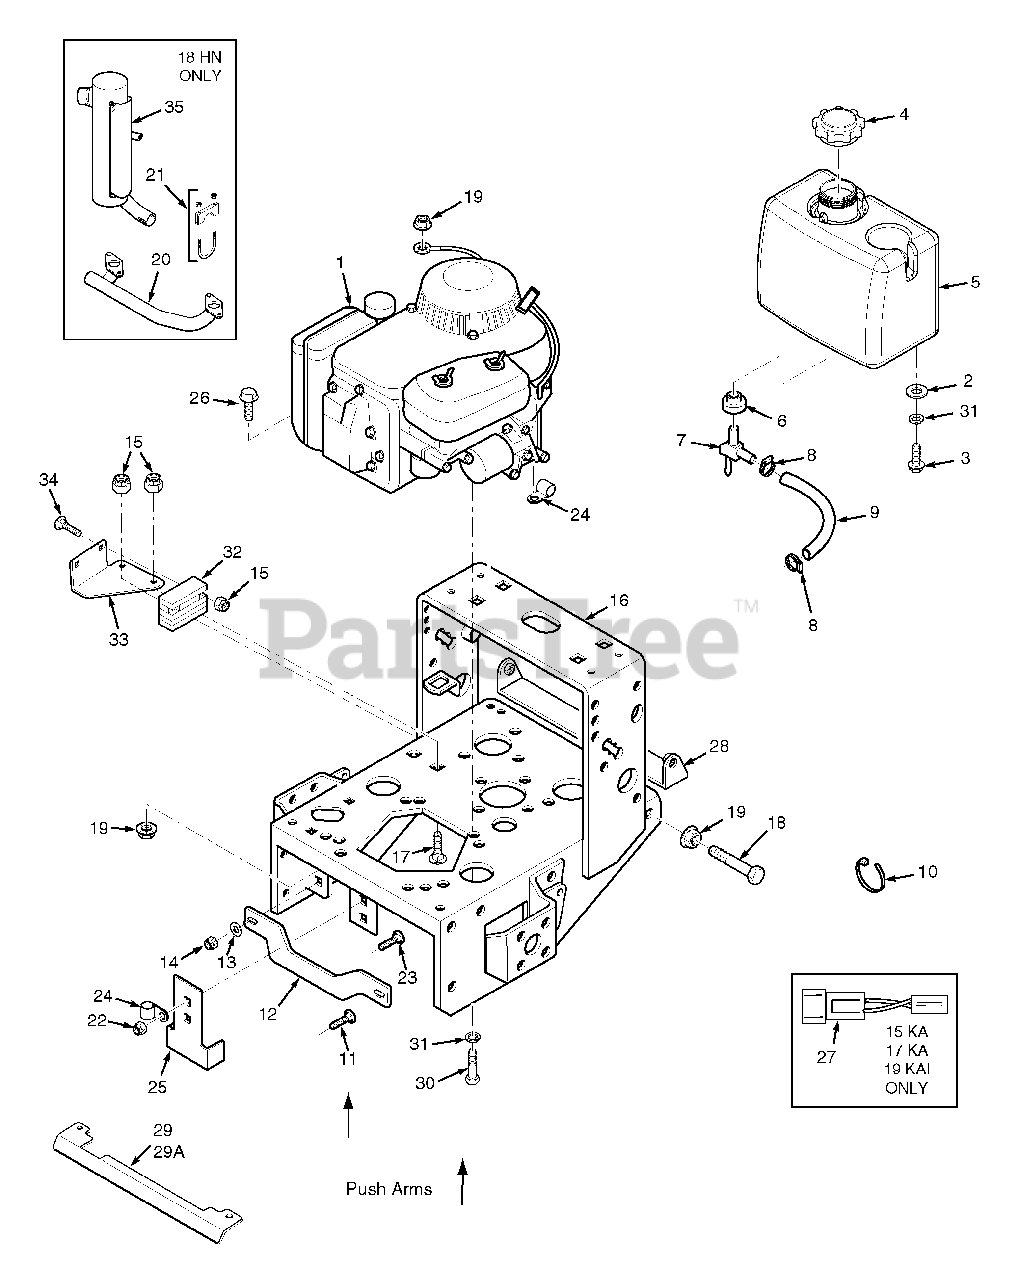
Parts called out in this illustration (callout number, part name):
1	Engine, 15KA Kawasaki
2	Flatwasher, 5/16 (.375 x .875 x .083)
3	Capscrew, 5/16-18 x 1" Hex Head
4	Cap, Fuel Tank
5	Fuel Tank Assy. (incl. 8, 9)
6	Bushing
7	Valve, Fuel Shut-off
8	Clamp, Fuel Hose
9	Fuel Hose, 1/4 ID x 23"
10	Cable Tie
11	Carriage Bolt, 3/8-16 X 1-1/4"
12	Brace
13	Flat Washer .391 x .938 x .105
14	Nut, 3/8-16 Elastic Stop
15	Nut, 1/4-20 Elastic Stop
16	Engine Deck, 16" Wide, w/decals
17	Bolt, 1/4-20 x 1-1/4" Carriage
18	Bolt, 5/16-18 x 2" Hex Head
19	Nut, 5/16-18 Serr. Flange
20	Manifold, Exhaust
21	Clamp, Muffler
22	Nut, 5/16-18 Elastic Stop
23	Carriage Bolt, 5/16-18 x 1"
25	Clutch Bracket
26	Cap Scrw, 5/16-18 x 1.50" Sr. Flg
27	Wire Hrns. Adapter, 15KA, 17KA & 19 KAI
28	Pulley Guard, 16" Frame
29	Heatshield
29A	Heatshield
30	Bolt, 5/16-18 x 1" Serrated Flange Hex Head
31	Lock Washer 5/16"
33	Mounting Bracket, Rectifier
34	Bolt, 1/4-20 x 1" Carriage
35	Muffler
